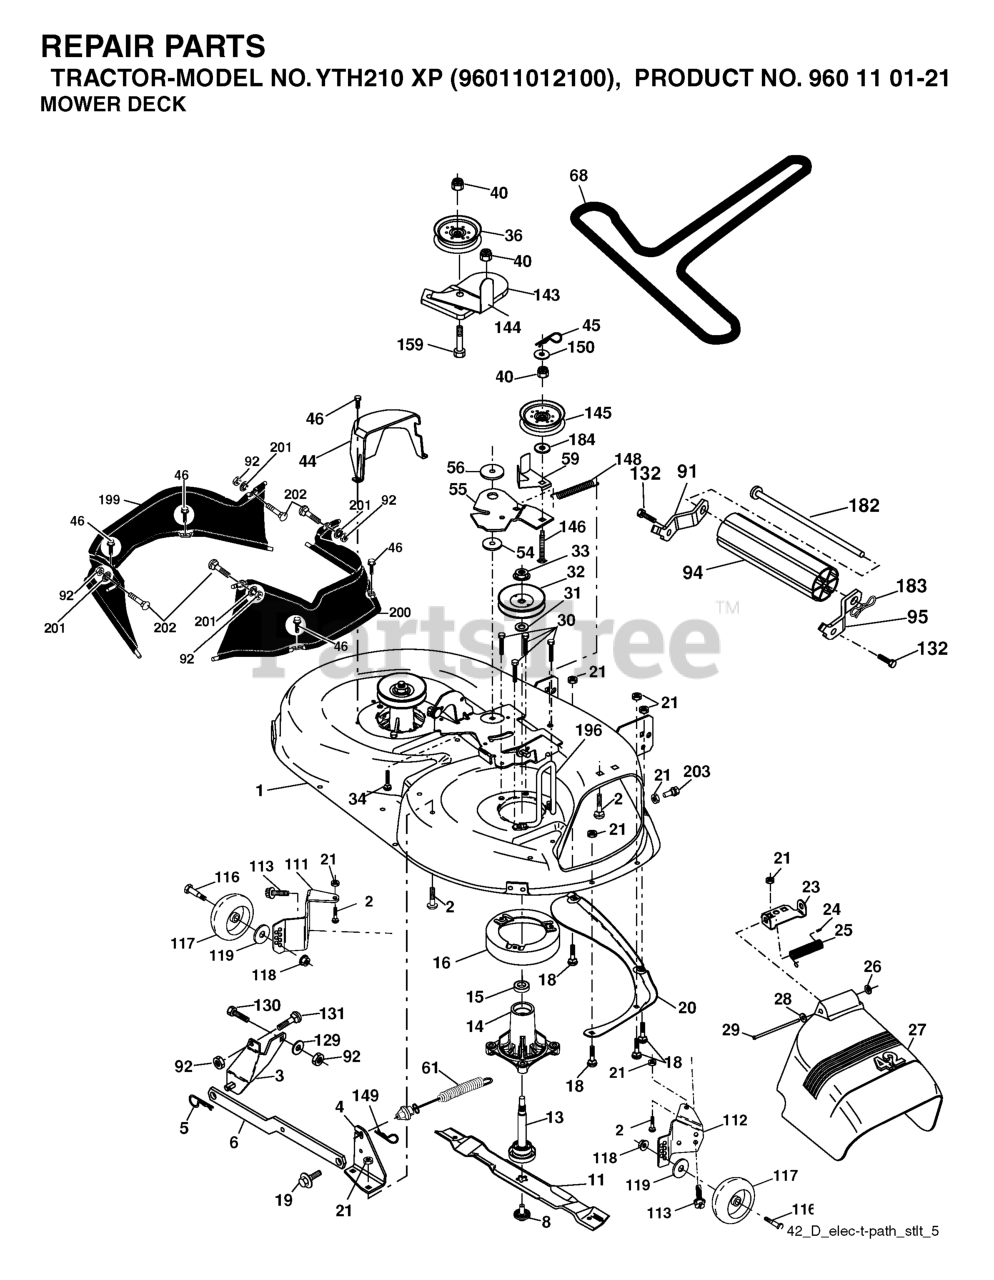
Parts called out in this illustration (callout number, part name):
1	42" DECK KIT
2	RP BOLT 5/16-18 X3/4 ZN/YEL GR
3	BRKT ASM SWAY BAR
4	BRACKET SWAY BAR 42" DECK
5	RETAINER-SPRNG RB
6	BAR SWAY DECK
8	BOLT.WASHER.ASM.7/16-2
9	LOCKWASHER
10	WASHER.BLADE
11	42" HI-LIFT BLADE
13	SHAFT.ASM.MDRL.N/GREASE.38
14	RP.HOUSING.MANDREL.4PT.
16	STRIPPER.MANDREL.ROUND.BLACK
18	BOLT
19	BOLT SHD 5/16-18
20	BAFFLE.VORTEX
21	LOCKNUT
23	BRKT, DEFL. MOWER
24	CAP-SLEEVE LT
25	SPRING TORSION
26	NUT PUSH M
27	SHIELD ASM.DFLCTR MOWER 42"BLK
28	Washer 11/32 x 5/8 x 16 Ga SD
29	ROD.HINGE
30	SCREW, WASHER HEAD
31	WASHER.SPACER.MANDREL
32	PULLEY/MANDREL
33	NUT.FLANGE.LOCK.TOP
34	BOLT.3/8-16X1.50
36	FLAT IDLER PULLEY
40	NUT LOCK FLG 3/8-16 UNC
44	GUARD MANDREL LH BLACK
45	RETAINER M
46	SCREW.1/4-20X5/8
55	ARM IDLER 42" MOWER LT/YT
56	SPACER.RETAINER.MOWER
59	GUARD, BELT
61	SPRING EXT ELEC CLUTCH
91	BRACKET ASM NOSEROLLER LH
92	NUT
94	NOSE ROLLER
95	BRACKET ASM NOSEROLLER RH
111	BRACKET, WHEEL
112	BRACKET, WHEEL
113	BOLT.5/16HEX.WHS.HD
116	BOLT M
117	WHEEL.GAGE.HALF.SPOKED
118	LOCKNUT
119	WASHER.5/16.FLAT.STE.STD.
129	WASHER
131	BOLT D
132	SCREW, 3/8-16X3/4
143	BRACKET, ARM IDLER
144	DNO KEEPER.BELT.42".CLUTCH.CBL
145	PULLEY
146	BOLT, CARRIAGE IDLER BLACK
148	IDLER RETURN SPRING
149	SPRING.RETAINER.YELLOW.ZINC
182	ROD ROLLER NOSE STANDARD
183	PIN.COTTER.7/16.BOW TI.
184	WASHER
201	PUSH.NUT.ROUND.3/8.DIAM
202	BOLT D
